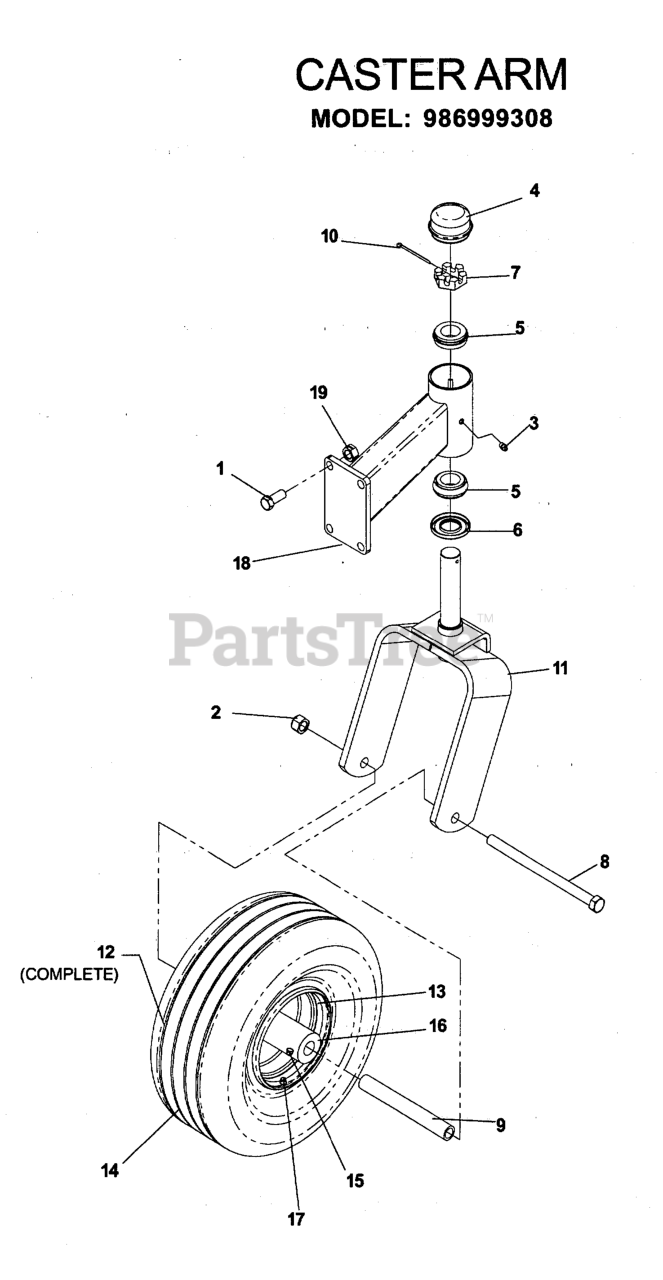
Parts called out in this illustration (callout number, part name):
1	HCS 7/16-14 X 1 GR 5 ZD
2	NUT 1/2-13 HEX NYLOC ZD
3	ZERK
4	GREASE CAP
5	TAPERED ROLLER BRG
7	NUT 1"C HEX SLOTTED
8	SCREW 1/2C X 7 1/2 HEX CAP
9	SPACER, CASTER
10	COTTER PIN 1/8 X 2
11	CASTER YOKE ORANGE
12	TIRE.ASSEM.13X5-6.SMOOTH.SILVE
13	RIM
14	TIRE - FRONT
15	ZERK 1/8 NPT
16	BEARING RETAINER
17	VALVE STEM TR-412
18	FRONT CASTER ARM, ORG
19	NUT 7/16C CENTERLOCK
